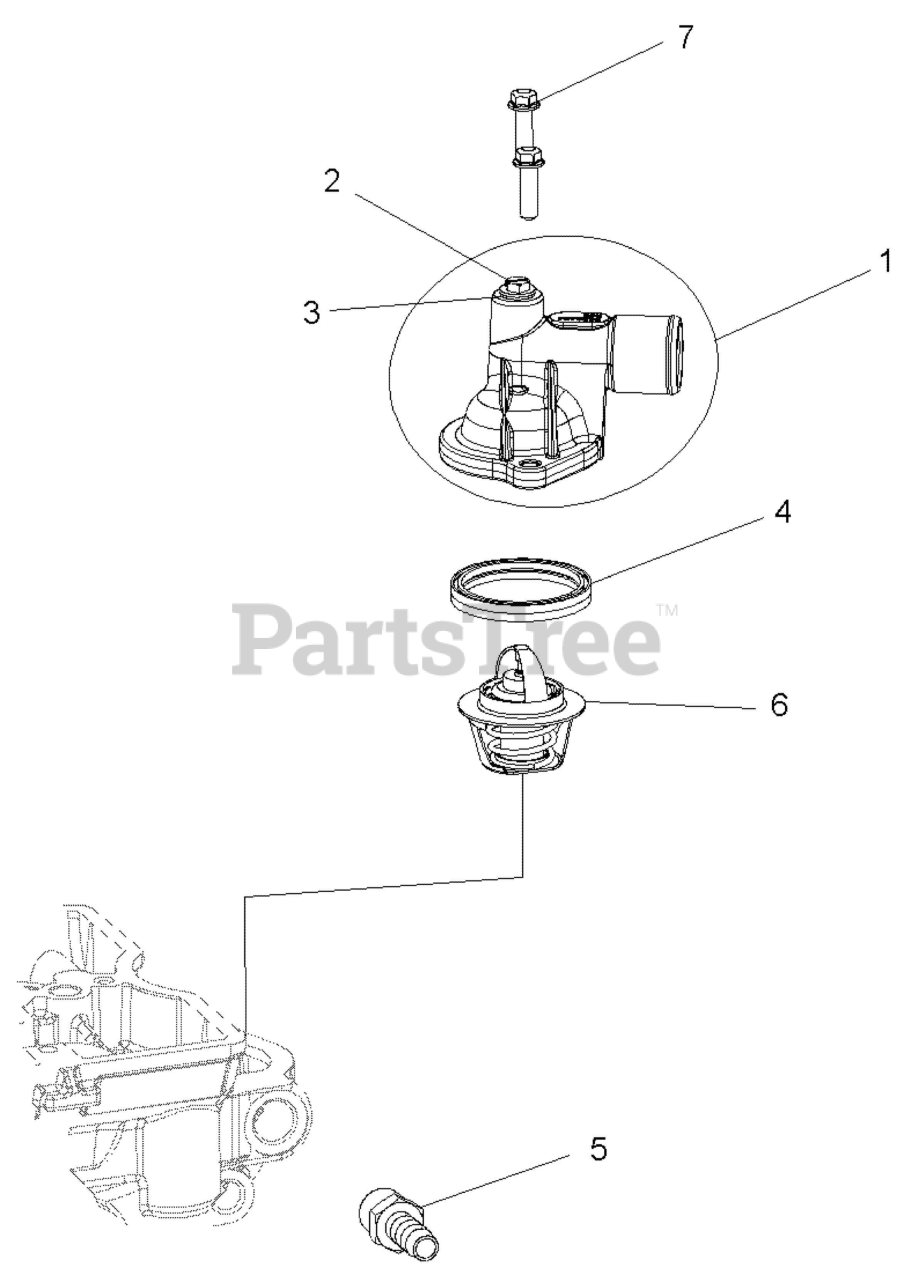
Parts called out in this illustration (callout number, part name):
1	ASM-THERMOSTAT COVER W/BLEED
1	COVER-THERMOSTAT,ANGLED,MACH
2	SCR-M6X1.0X13,SL/HX/FL-Z,BLEED
3	WASHER-FLAT
4	SEAL-THERMOSTAT
5	FITTING-3/8NPTFX1/2 HOSE BARB
6	THERMOSTAT-44M FLANGE,180F
7	SCR-M6X20,HXFLG,0600214
